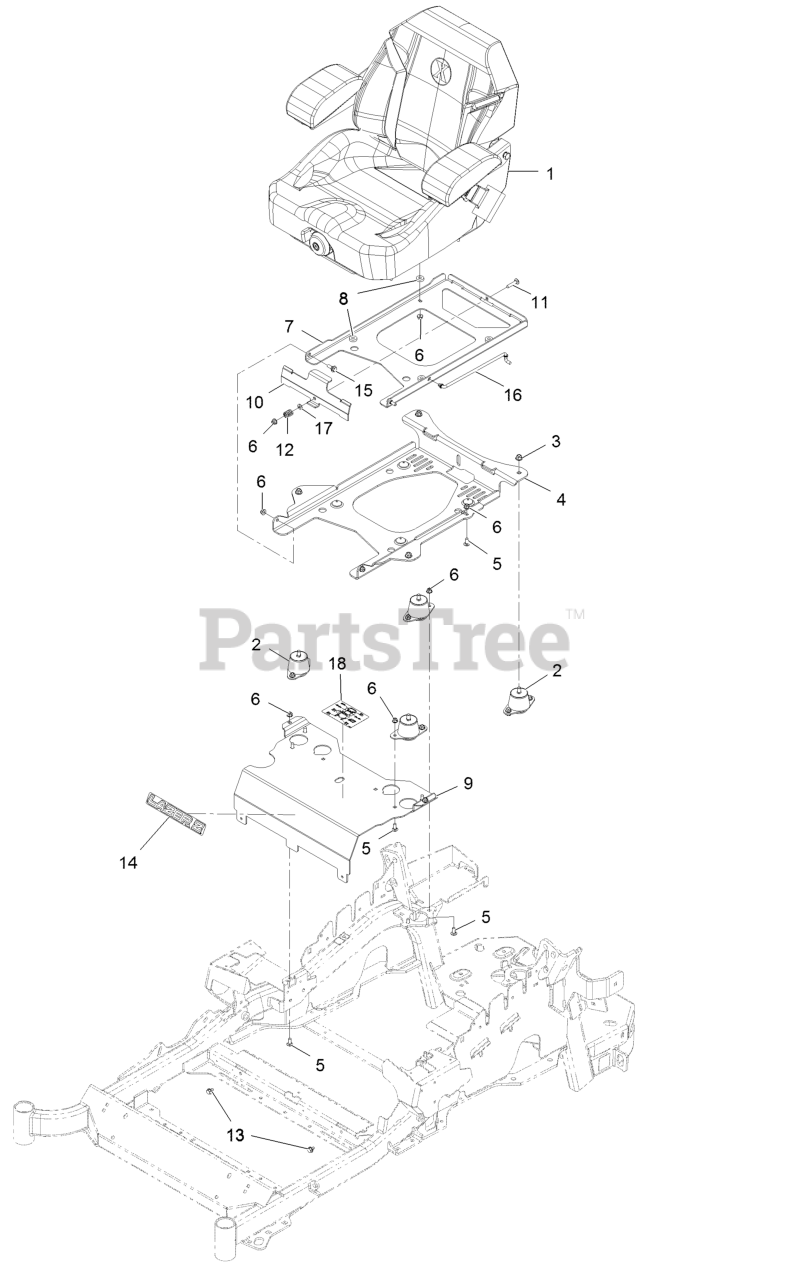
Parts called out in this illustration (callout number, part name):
1	Kit-Suspension Seat
2	Isolator-Seat
3	Nut-Nyloc 3/8-16 Flg
4	Plate-Tilt, Seat Support
5	Bolt-Carriage 5/16-18 X 3/4 Short Neck
6	Nut-Nyloc 5/16-18 Flg
7	Plate-Frame, Seat
8	Spacer-Pin, Mounting
9	Panel-Front, Seat Mount
10	Plate-Latch, Seat
11	Bolt-Carriage 5/16-18 X 1 1/2
12	Spring-Compression
13	Screw-HWH 5/16 X 1/2 Tf
14	Decal, Lazer Model
15	Screw-Shoulder
16	Rod-Prop
17	Washer-5/16 SAE
18	Decal-Service Aid
